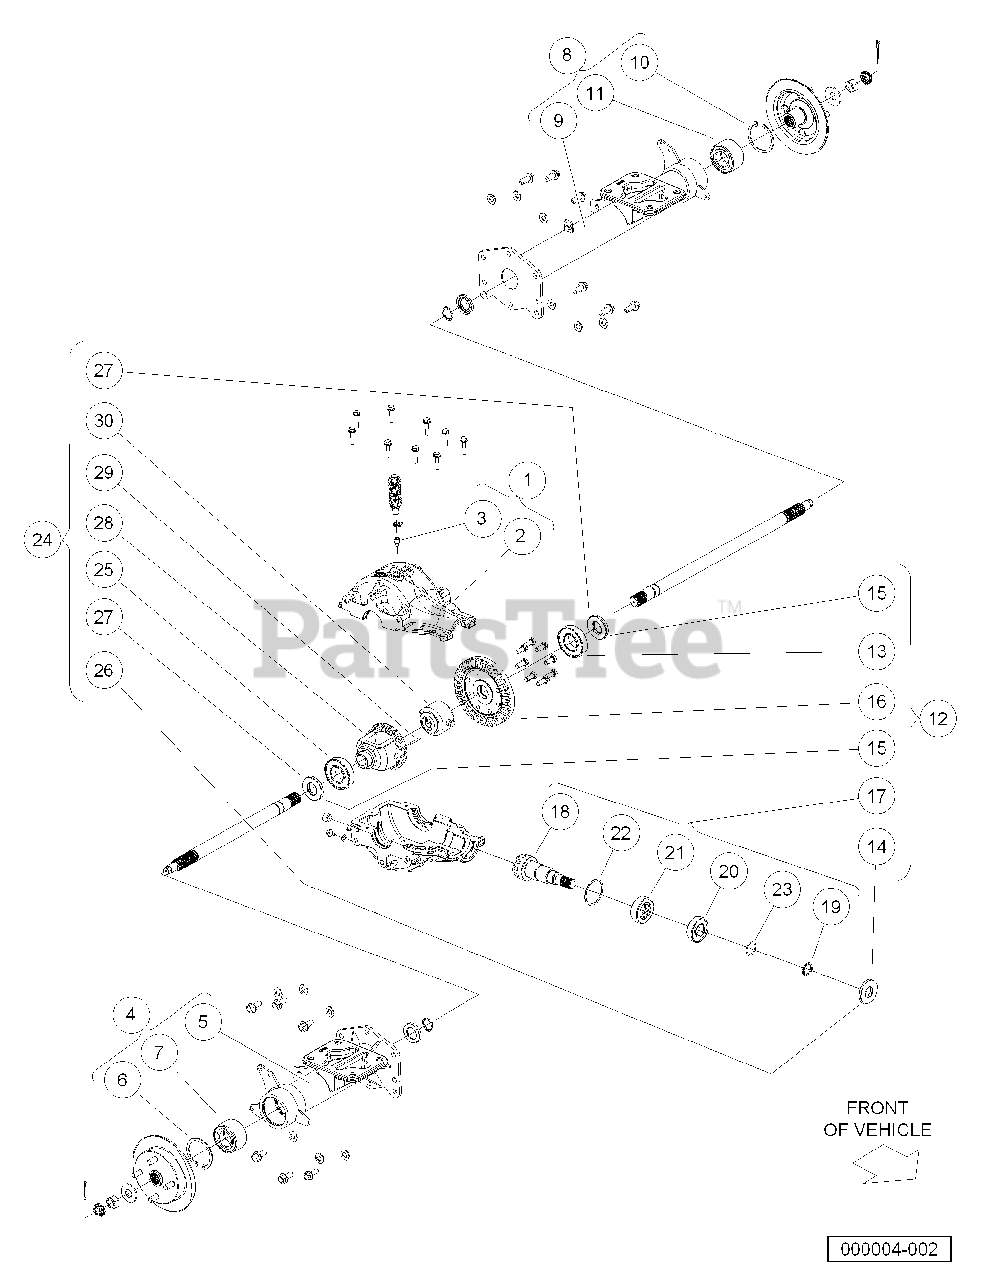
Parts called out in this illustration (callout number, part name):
1	Asm, Gearcase, Upper
2	Gearcase, Upper, Machined
3	Vent, Top, Upper Housing
4	Asm, Axle Tube, RH
5	Weldment, Axle Tube Rh
6	Ring, Retaining, Internal
8	Asm, Axle Tube, LH
9	Weldment, Axle Tube Lh
10	Ring, Retaining, Internal
12	Kit, Rear Axle Gear Repair
13	Bearing, Ball
14	Seal, Dual-Lip 25x 62x 7tc
15	Seal, Dual-Lip 30x 62x 8tc
17	Asm, Pinion W/ Bearings
18	Pinion, I0t Machined
19	Ring, Retaining, External
20	Bearing, Ball
21	Bearing, Needle, Drawn Shell
22	Washer, 2.625 X 2.367 X .06
23	Shim, 1.50 X 1.189 X .008
24	Asm, Differential & Carrier
25	Bearing, Ball
26	Seal, Dual-Lip 25x 62x 7tc
27	Seal, Dual-Lip 30x 62x 8tc
28	Housing, Differential, Mach
29	Pin, Dowel, 4 X 35
30	Asm, Locker, Nongrease/Spacers
